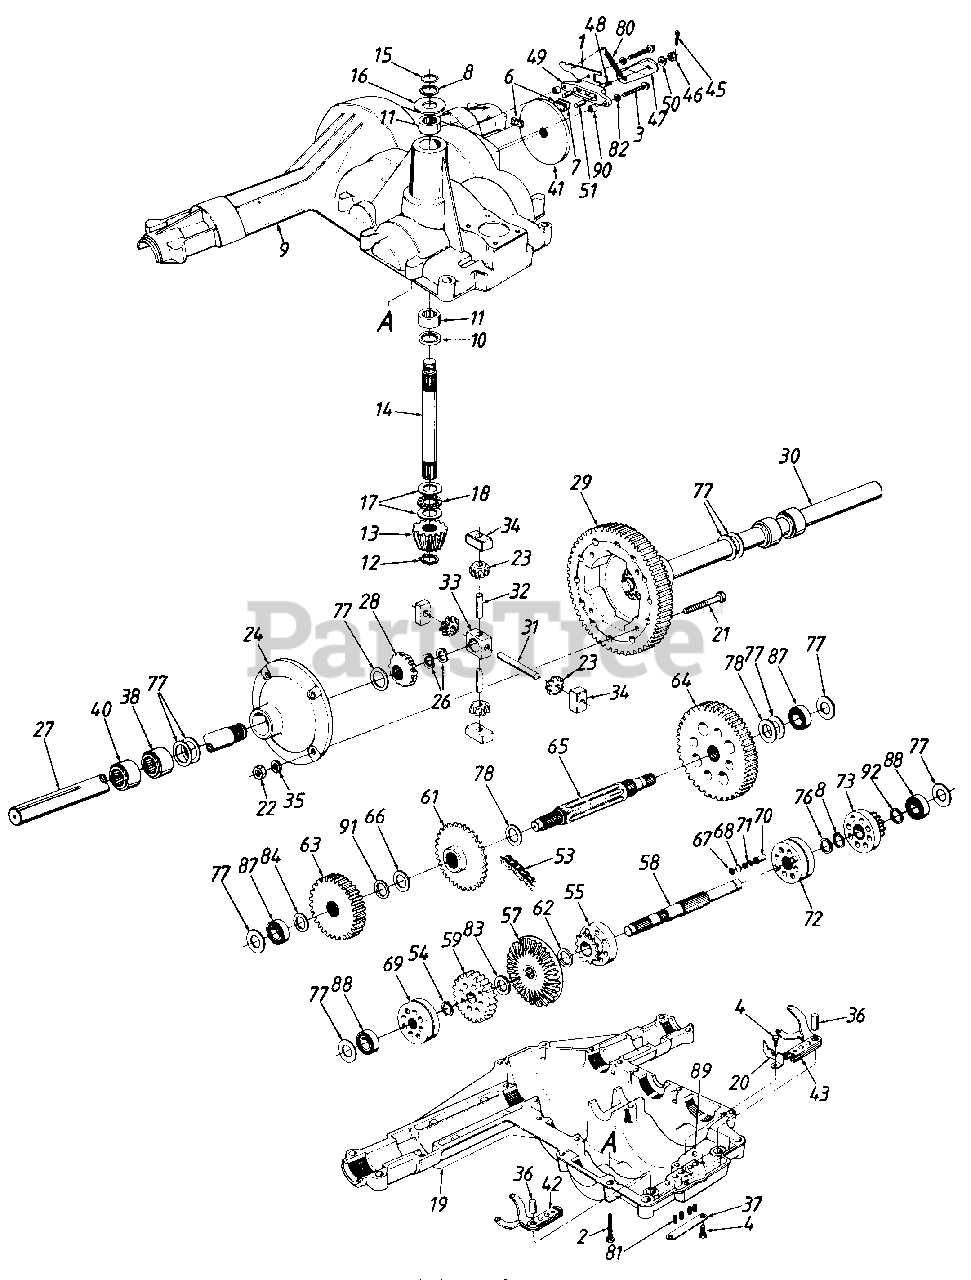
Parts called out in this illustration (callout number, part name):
1	Brake Return Bracket
2	Hex Bolt 1/4-20 x 1.25" Lg.
3	Hex Bolt 1/4-20 x 1.5" Lg. (Grade 5)
4	Tap Scr. 1/4-20 x .38" Lg.
6	Brake Puck
7	Puck Plate
8	Retainer Ring
9	Upper Housing
10	Oil Seal
11	Needle Brg. 5/8" I.D. x 7/8" 0. D
12	Snap Ring
13	Input Pinion 15T
14	Input Shaft
15	Wire Ring
16	Thrust Washer 5/8" I.D.
17	Thrust Washer
18	Thrust Bearing
19	Lower Housing
20	Shift Guide
21	Hex Bolt 3/8-24 x 2.0" Lg.
22	Hex L-Nut 3/8-24 Thd. (Grade 5)
23	Differential Gear 1OT
24	Differential Housing Cover Ass'y.
26	Retainer Ring
27	Axle R.H.
28	Differential Gear 14T
29	Differential Bull Gear 60T
30	Axle L.H.
31	Cross Shaft
32	Cross Shaft Special
33	Differential Pinion Block
34	Differential Thrust Block
35	Spr. Wash. .39" I.D. x .62" O.D.
36	Shift Pin
37	Spring Plate
38	Axle Bearing Ass'y.
40	Axle Bearing Ass'y.
41	Brake Disc
42	Shift Arm Ass'y. R.H.
43	Shift Arm Ass'y. L.H.
45	Cotter Pin 3132" Dia.
46	Castle Nut 5/16-24 Thd.
47	Brake Actuating Arm
48	Sq. Hd. Bolt 5/16-24 Thd.
49	Brake Yoke
50	Fl-Wash. 11/32" I.D. x 7/8" O.D.
51	Brake Actuating Pin
53	#420 Chain 1/2 Pitch x 28 Links
54	Retainer Ring
55	Reverse Sprocket Ass'y.
57	Bevel Gear 47T
58	Drive Shaft
59	Spur Gear Ass'y.
61	Sprocket 22T
62	Fl-Wash. .81" I.D. x 1.18" O.D.
63	Spur Gear 31 T
64	Spur Gear 45T
65	Output Shaft 9T
66	Spacer
67	Internal Retainer Ring
68	Plug .44" Dia.
69	Forward Shift Collar
70	Drive Pin
71	Drive Spring
72	Creeper Shift Collar
73	Creeper Collar Plate Ass'y.
76	Fl-Wash. .65" I.D. x .97" O.D.
77	Fl-Wash.
78	Fl-Wash. 1.0" I.D. x 1.56" O.D.
80	Ext. Spring 1.14" Lg.
81	Detent Spring
82	L-Wash. 1/4" I.D.
83	Fl-Wash. 5/8" I.D. x 1.0" O.D.
84	Fl-Wash. .68" x 1.12"
87	Ball Brg. .669" I.D.
88	Ball Bearing
89	Ball Detent .25" Dia.
90	Spacer .254" I.D. x .5" O.D.
91	Fl-Wash. .69" I.D. x 1.06" O.D.
92	Fl-Wash.
